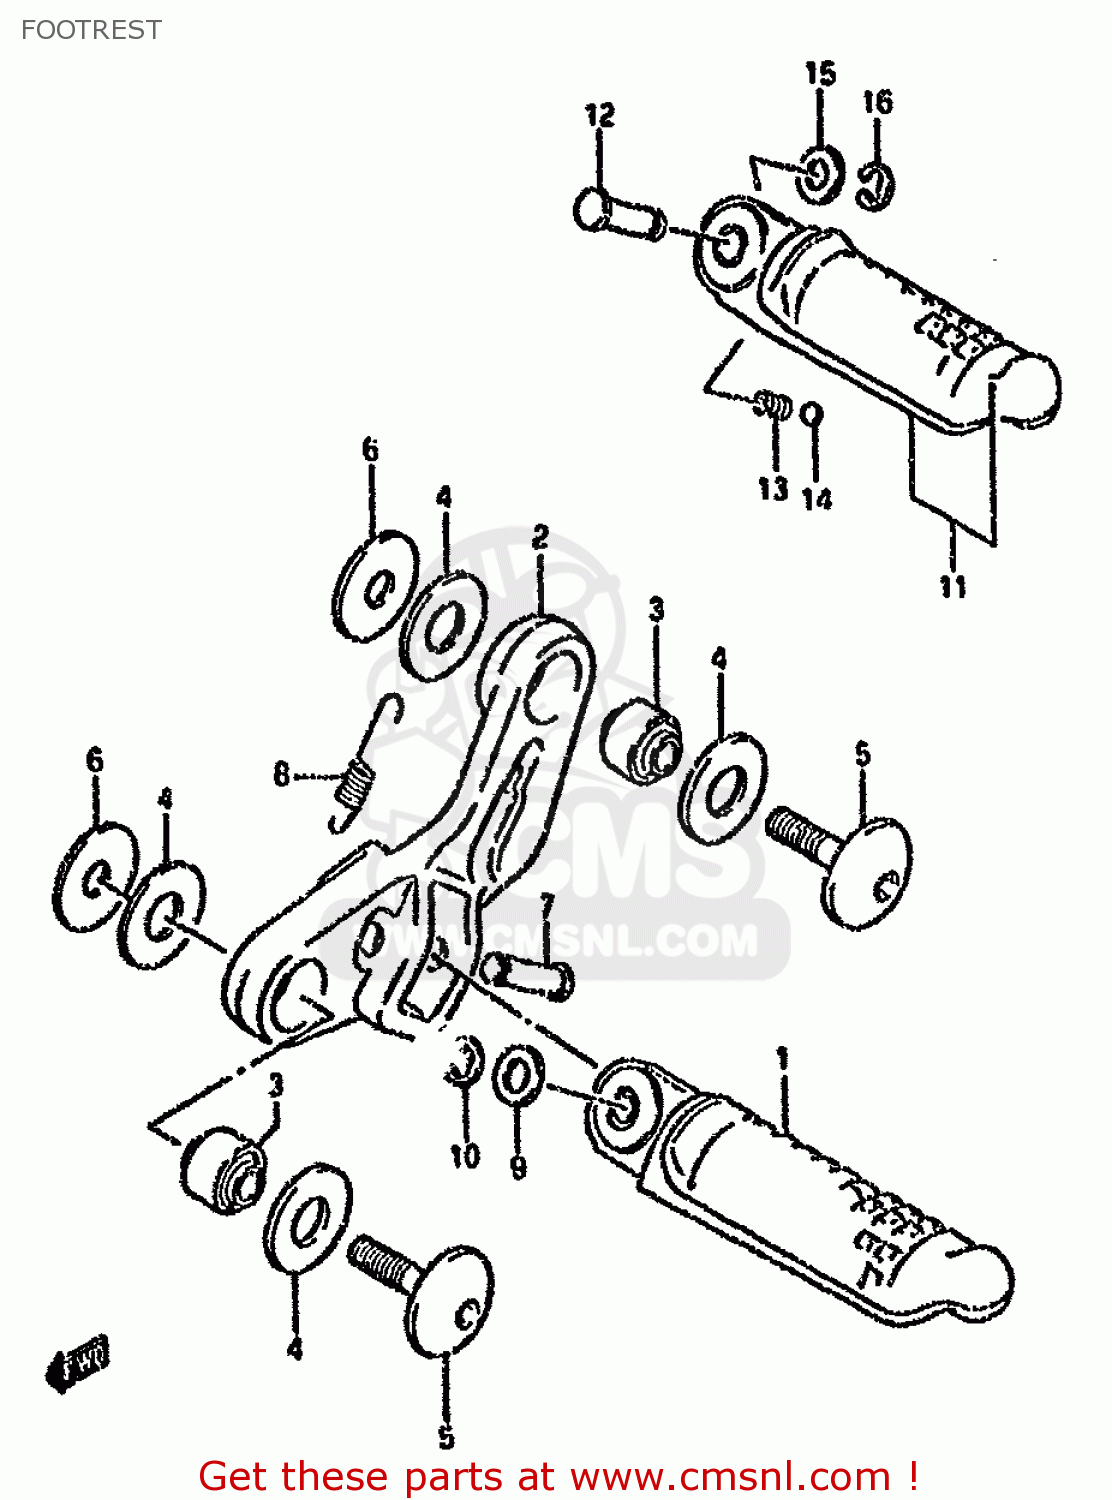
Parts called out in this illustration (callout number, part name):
1	BAR,FRONT FOOTREST,LEFT
2	HOLDER,FR FOOTREST,R
3	BUSH(8.4X20X18)
4	WASHER(12.5X30X2)
5	BOLT(8X31)
6	WASHER(8.5X30X2.3)
7	PIN(8X33.2)
8	SPRING
9	WASHER
10	E.RING
11	BAR,PILLION FOOTREST,R
12	PIN
13	SPRING
14	BALL
15	WASHER
16	E.RING
